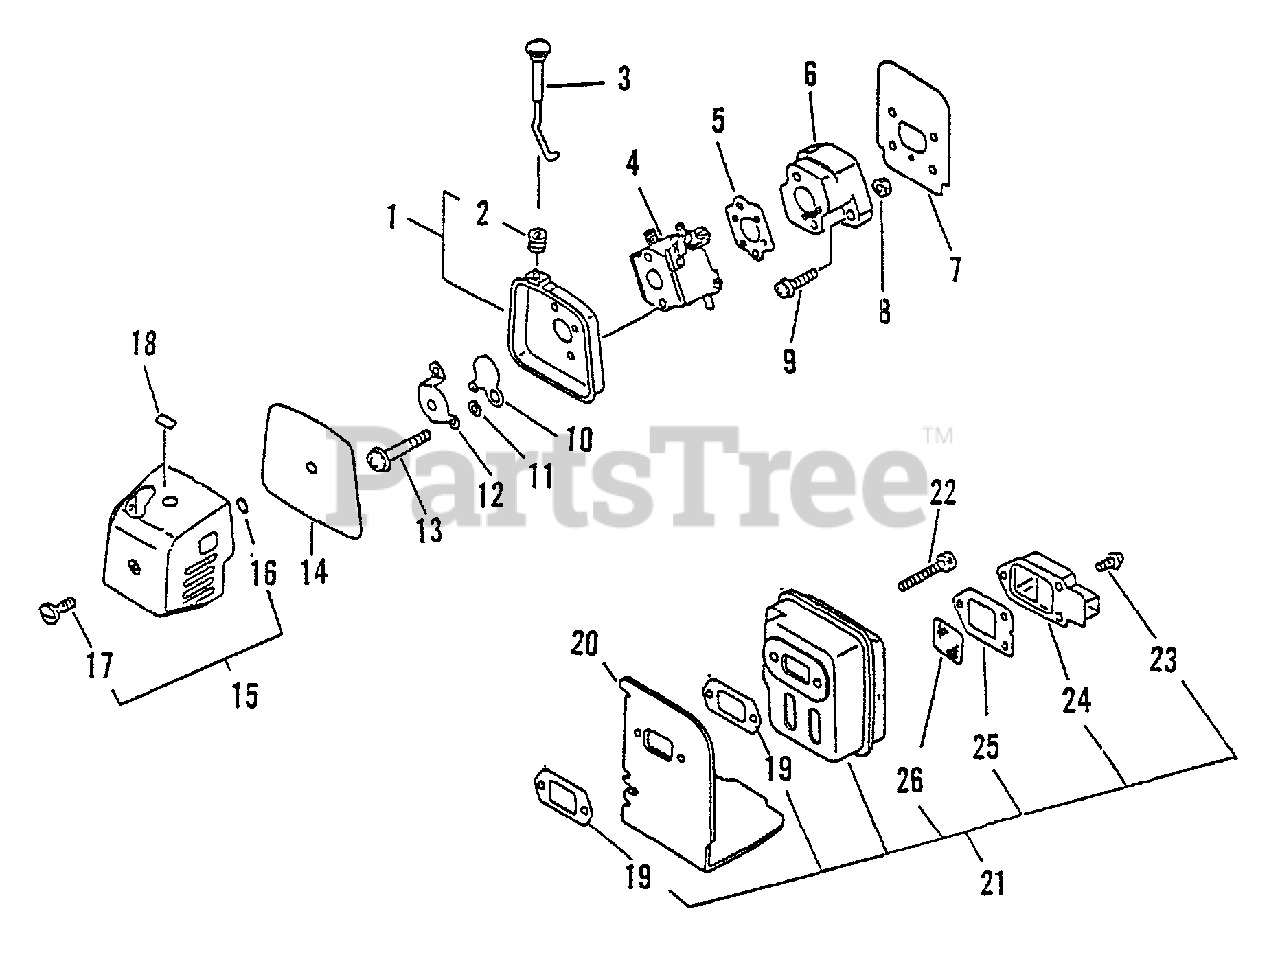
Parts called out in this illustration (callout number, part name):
1	CASE, AIR FILTER
3	ROD, CHOKE
4	CARBURETOR C1U-K12
5	GASKET, INTAKE
6	INSULATOR, INTAKE
7	SHIELD, INTAKE
9	SCREW - 5X20
10	SHUTTER, CHOKE
11	WASHER - 5
12	BRACKET, AIR CLEANER
13	SCREW - 5X57
14	FILTER, AIR
15	AIR FILTER COVER ASSY
16	O-RING - 4
18	LABEL - CHOKE
19	GASKET, EXHAUST
20	COVER, EXHAUST
21	MUFFLER ASSY
22	SCREW - 5X55
22	WASHER - 5
23	SCREW - 4X10
24	GUIDE, EXHAUST - OUTER
25	GASKET, EXHAUST
26	SCREEN, SPARK ARRESTOR
